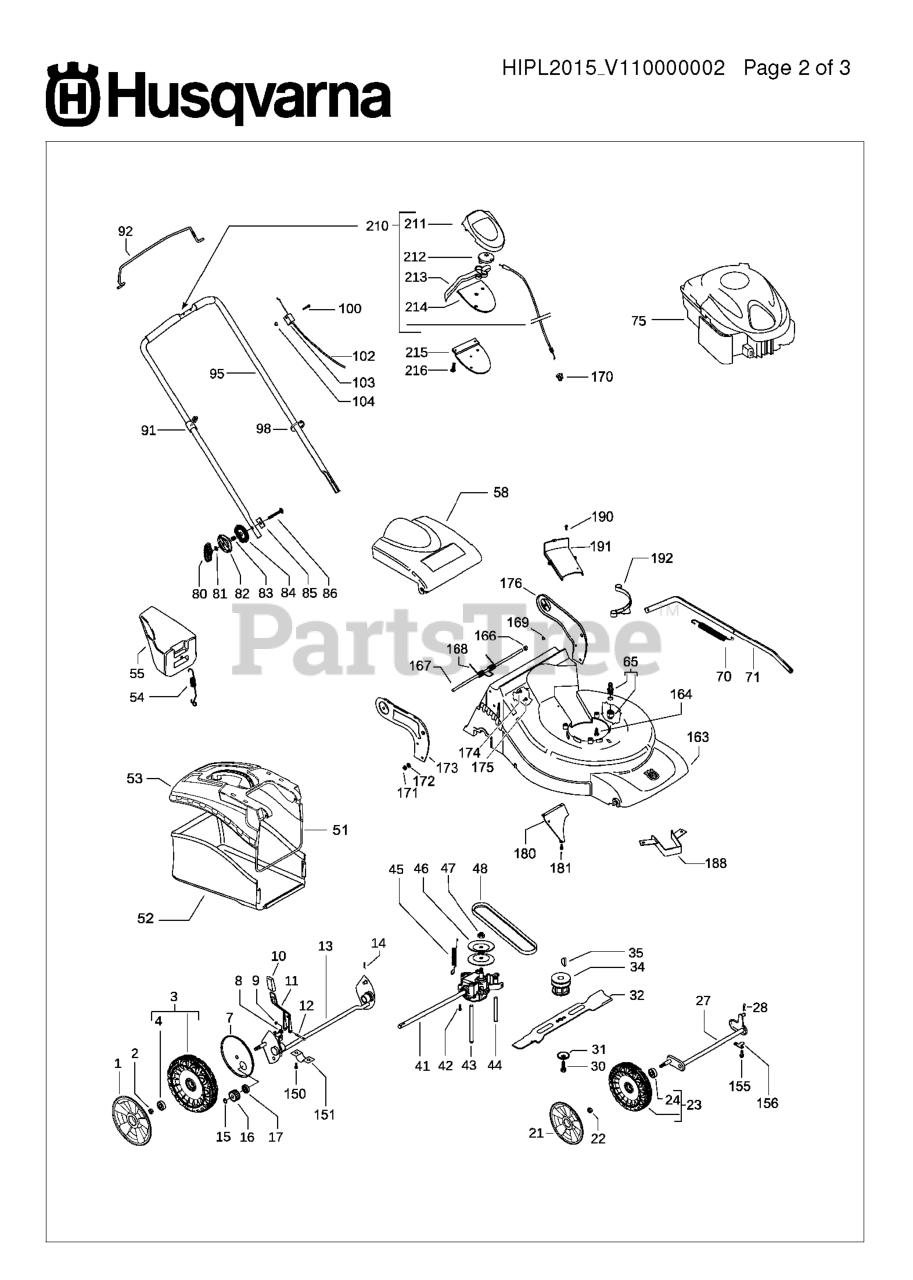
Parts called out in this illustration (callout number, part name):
51	FRAME 51 CAST
58	DEFLECTOR 51 CAST ORANGE
95	HANDLE ASSY
102	BRAKE WIRE
168	SPRING 51 CAST
211	COVER, DRIVE CONTROL, TOP
212	PULLEY.CAM.DRIVE.CONTROL.EZ
213	LEVER, DRIVE CONTROL
214	COVER, DRIVE CONTROL BOTTOM
215	BRACKET, DRIVE CONTROL
216	SCREW, PHILLIPS HEAD 10 X 5/8
